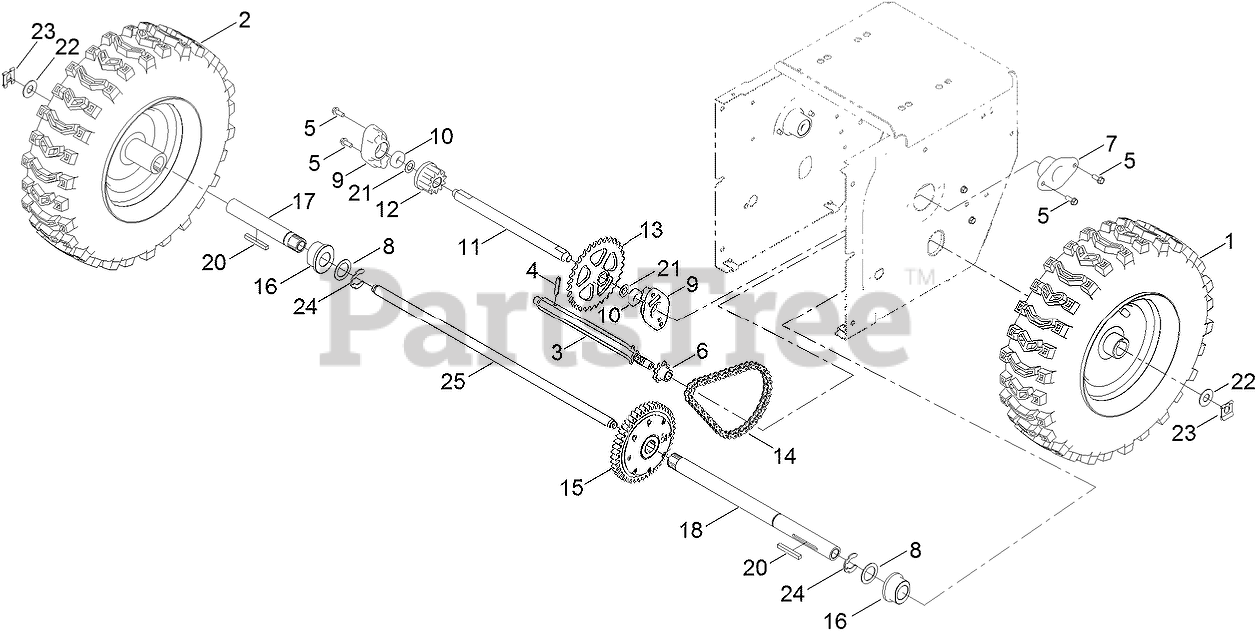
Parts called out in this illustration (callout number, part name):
1	LH WHEEL AND TIRE ASM
2	RH WHEEL AND TIRE ASM
3	SHAFT-HEX
4	PIN-ROLL, SLOTTED
5	SCREW-HWH
6	GEAR-PINION, 8 TOOTH
7	RETAINER-BEARING
8	WASHER-THRUST
9	RETAINER-BEARING, INTERMEDIATE
10	BEARING-WHEEL
11	SHAFT-INTERMEDIATE
12	TOOTH-GEAR, 11
13	SPROCKET-32T
14	CHAIN-ROLLER
15	TRANSMISSION-GT, DI310
16	BUSHING-AXLE
17	AXLE-TUBE, RH
18	AXLE-TUBE, LH
20	KEY-SQUARE
21	WASHER-PLAIN
22	WASHER
23	CLIP-PIN
24	RING-RETAINING
25	AXLE-BASE
